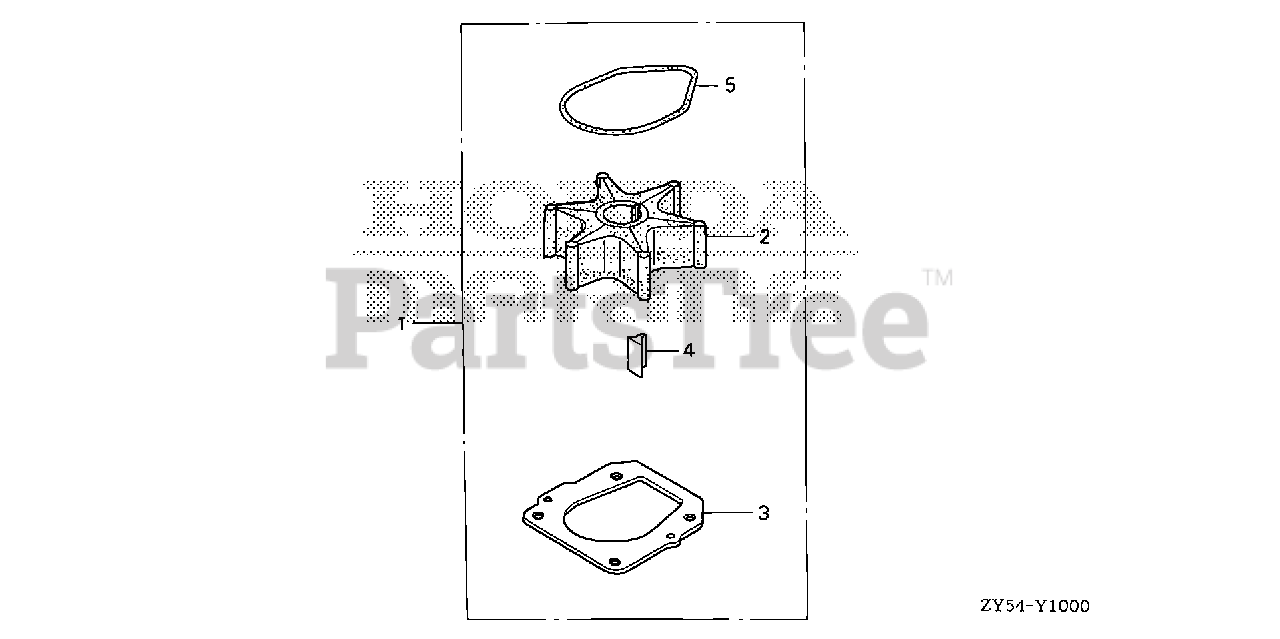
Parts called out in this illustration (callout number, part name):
1	PUMP KIT, IMPELLER
2	IMPELLER, PUMP
3	GASKET B, IMPELLER
4	KEY, WOODRUFF
5	O-RING, WATER PUMP
